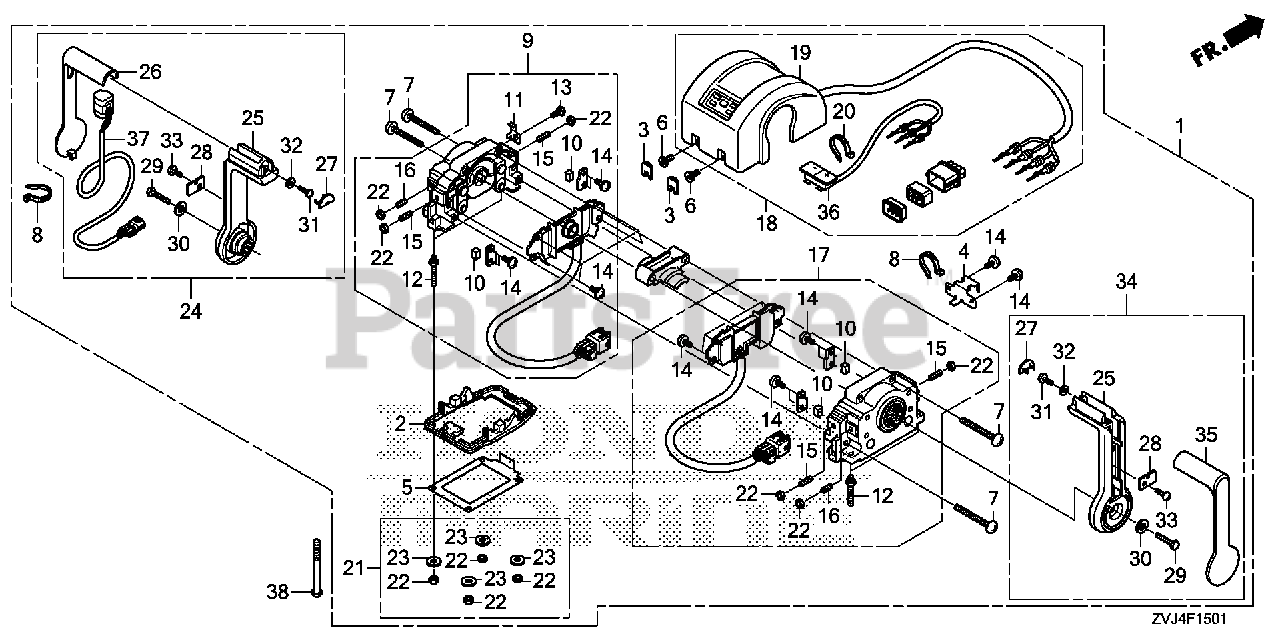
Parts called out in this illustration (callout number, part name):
1	BOX ASSY., REMOTE CONTROL (TOP MOUNT DUAL)(RH)
2	GASKET (TWIN)
3	COVER, CAP
4	PLATE, COVER FIX (TWIN)
5	SHEET, WATERPROOF (TWIN)
6	BOLT, SOCKET
8	BAND, NYLON
9	HOUSING ASSY., L.
10	SHOE, BRAKE
11	PLATE, HARNESS
12	BOLT, STUD
17	HOUSING ASSY., R.
18	COVER ASSY., TWIN
19	LED ASSY., COVER (T)
20	BAND, NYLON
21	NUT SET, MOUNTING
24	LEVER ASSY., L.
26	PANEL, LEVER (POWER TRIM-TILT)
27	CAP, LEVER
28	PLATE, LEVER PANEL
34	LEVER ASSY., R.
35	PANEL, LEVER
36	SWITCH ASSY., SELECT
37	SWITCH ASSY., POWER TRIM-TILT
38	SCREW, PAN (5X65)
